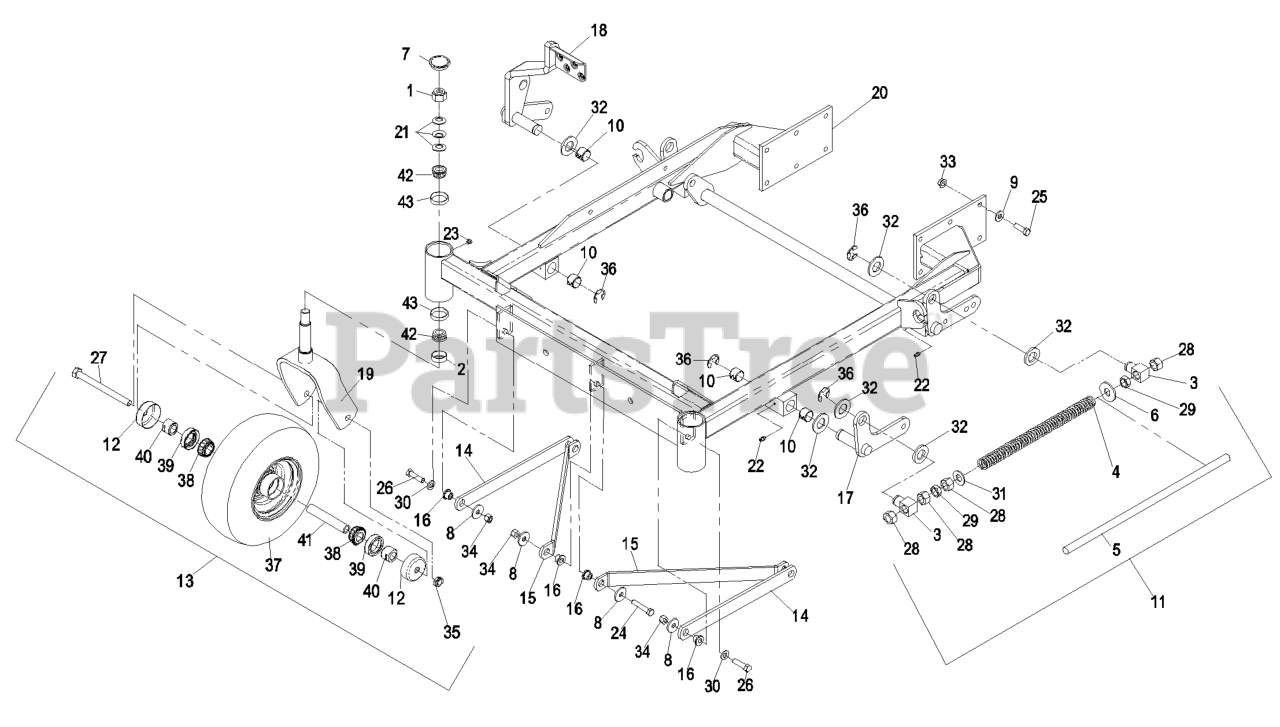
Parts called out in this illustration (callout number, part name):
1	NUT-LOCK, NI
2	SEAL-GREASE
3	SWIVEL-DECK MOUNT, REAR
4	SPRING-COMPRESSION
5	ROD-LIFT, DECK
7	CAP-GREASE
9	WASHER-BELLEVILLE
10	BUSHING,SPRING
11	FRONT SPRING ASM
12	GUARD-SEAL
13	WHEEL AND TIRE ASM
14	FLAT,STRUT
15	FLAT,STRUT ANGLED
16	SPACER-STRUT
17	WLD,SHAFT LH
19	FORK-CASTER
20	ASM,FRONT FRAME LCT483
21	WASHER-BELLVILLE
22	FITTING-GREASE
24	SCREW-HH
25	SCREW-HH
26	SCREW-HH
27	SCREW-HH
28	NUT-HEX
29	NUT-JAM
30	WASHER-FLAT
31	WASHER-FLAT
32	WASHER-FLAT
33	NUT-HHF, WHIZ
34	NUT-LOCK, NI
35	NUT-HEX
36	RING-RETAINING, EXT
38	BEARING-CONE, TAPERED ROLLER
39	SEAL-CASTER
40	SPACER-NUT
42	Cone-Bearing Tapered Roller
43	CUP-BEARING
